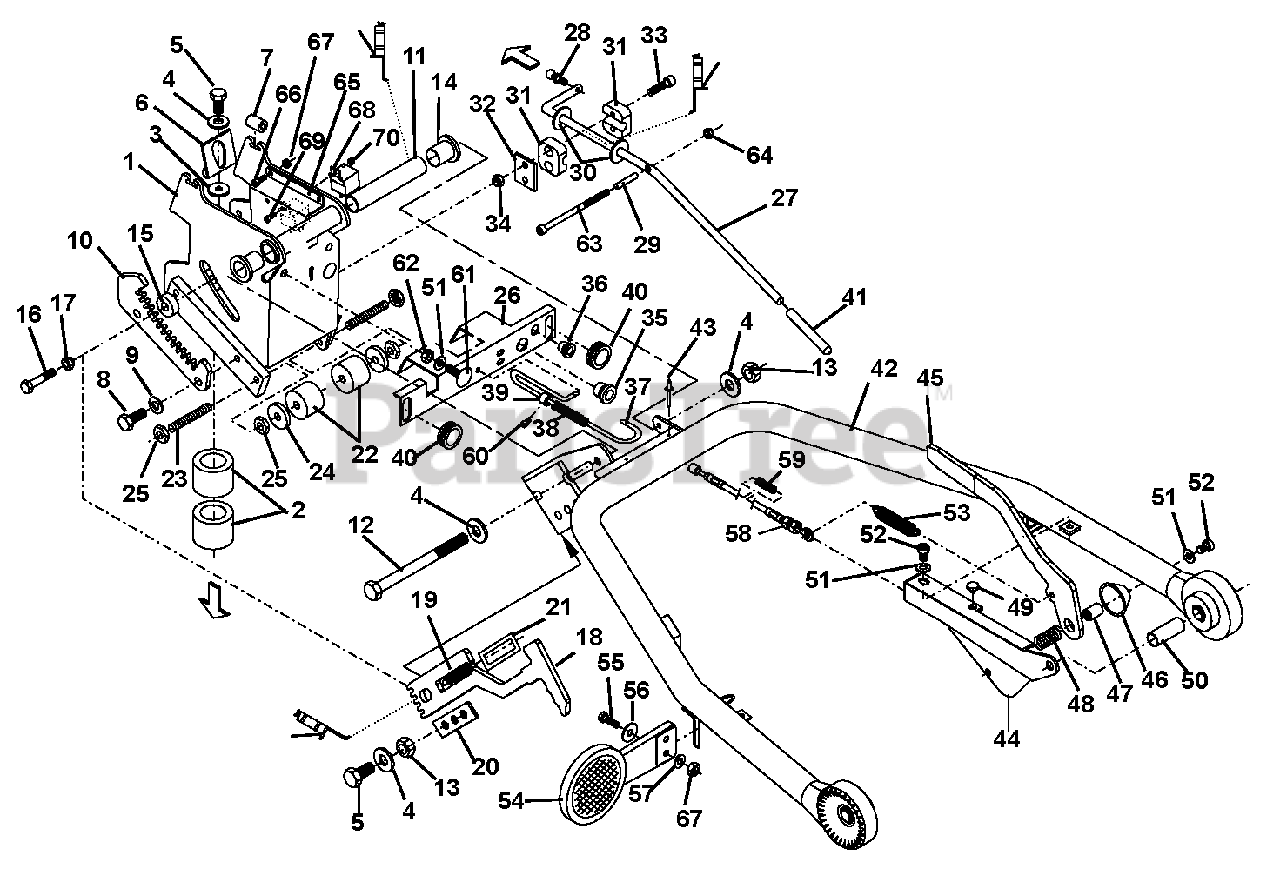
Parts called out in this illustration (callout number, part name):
1	Support Handle (Includes Item 2)
2	Silentbloc
4	Turnbuckel, D6796 13,0 x 293,0
5	Bolt, Hex, D933 M12 x 30
6	Fish-Plate
8	Hex Bolt, D933 M10 x 25 10.9
9	Washer, FORM Steel 10.2/20.25 x 1.6
12	Screw, Cylinder, D912 M12 x 170
13	Hex Nut, D6915 M12
14	Bushing, 20/23/3021,5
16	Screw, D912 Metric 8 x 40A
17	Nut, Lock, D985 Metric 8
19	Spring Tension
20	Plate, Belt Guide
21	Sliding Washer
23	Threaded Pin, D913 M10 x 70
24	Washer, 11,5 x 35 x 6
25	Nut, Hex, D439B M10
26	Dash Panel Assembly
27	Control Rod
28	Joint Ball Pin, D71803 10 A
29	Dowel Pin, 6 x 40
30	Ring, Idler, Self Propelled 220
31	Clamp, PAAR
32	Plate, Weldment
33	Screw, D912 M6 x 35
34	Nut, Lock, D985 M6
37	Bar, Lock
38	Pressure Spring, 1,25 x 8 x 69
39	Adjust Ring
41	Knob, Plastic
43	Rivit, Blind
44	Control Guide Right
45	Lever, Brake
47	Bushing W/Tread
48	Spring, Pressure
49	Stop, Pressure Switch
51	Washer, M8
52	Screw, ISO7380 Metric 8 x 12
53	Spring, Tension
54	Rear Reflector, Left 140 x D 92
55	Hex Bolt, D933 Metric 5 x 20
56	Washer, D440 7 x 22 x 2
57	Washer, M6
58	Brake Cable
59	Spring Tension
60	Screw, Cylinder, D912 Metric 4 x 5
61	Truss Head Screw, D603 M8 x 20
62	Nut, Hex D934 M8
63	Screw, Cylinder, D912 M3 x 50
64	Nut, Lock, D985 M3
66	Screw, D912 Metric 6 x 15
67	Nut, Lock, D985 M6
69	Screw, D912 M5 x 12
70	Nut, Lock
